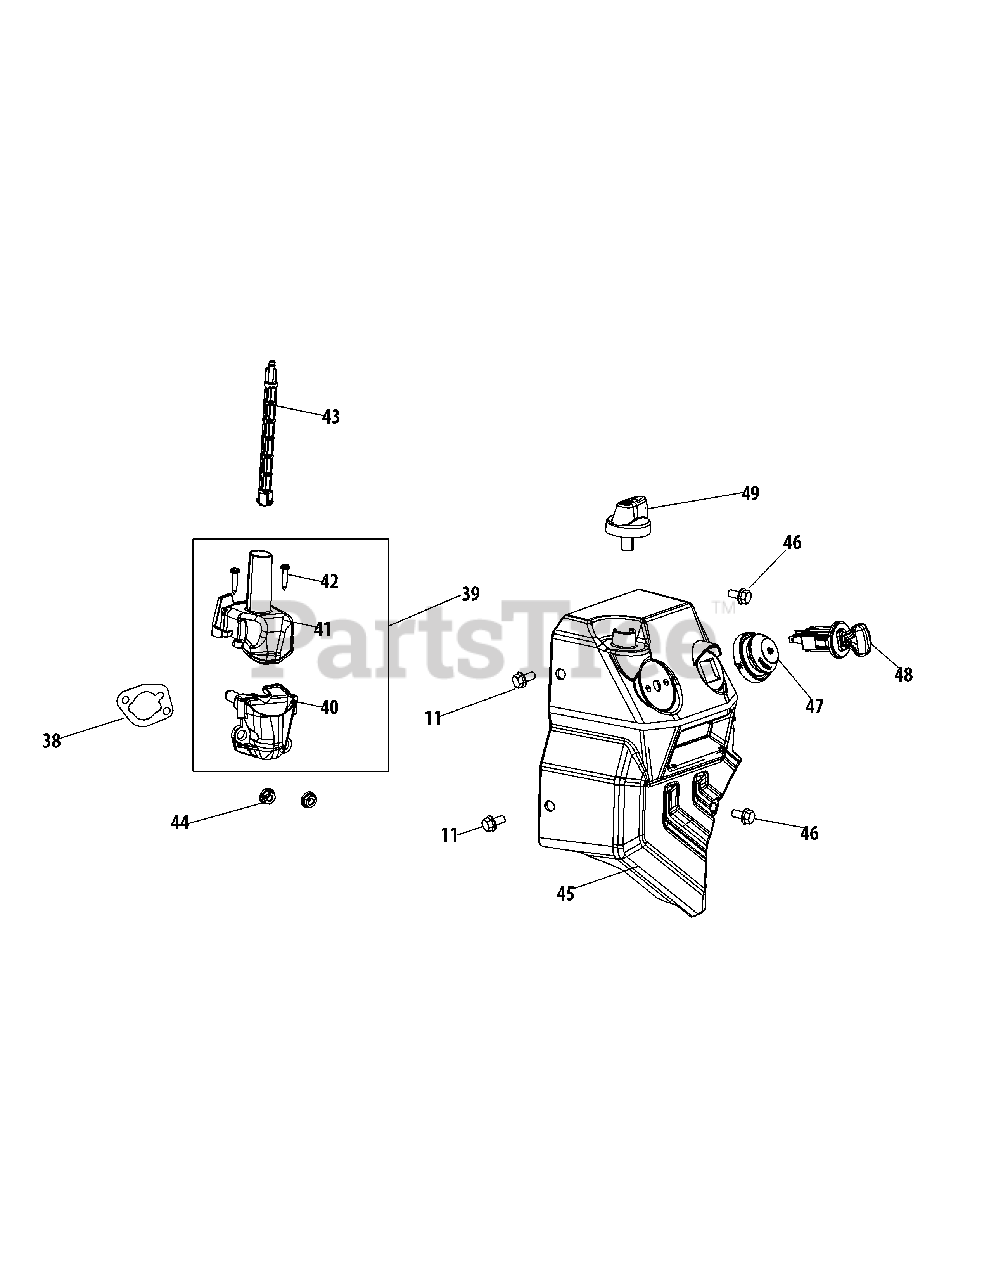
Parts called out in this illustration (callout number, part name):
11	Bolt, M6×12
38	Gasket, Air Filter
39	Heater Box
40	Air Filter Base
41	Upper Cover, Heater Box
42	Self-tappling Screw, ST4.2×16
43	Choke Linkage
44	Nut, M6
45	Control Panel
46	Bolt, M6×18
48	Stop Switch
49	Choke Lever
115	Stop Switch Key
